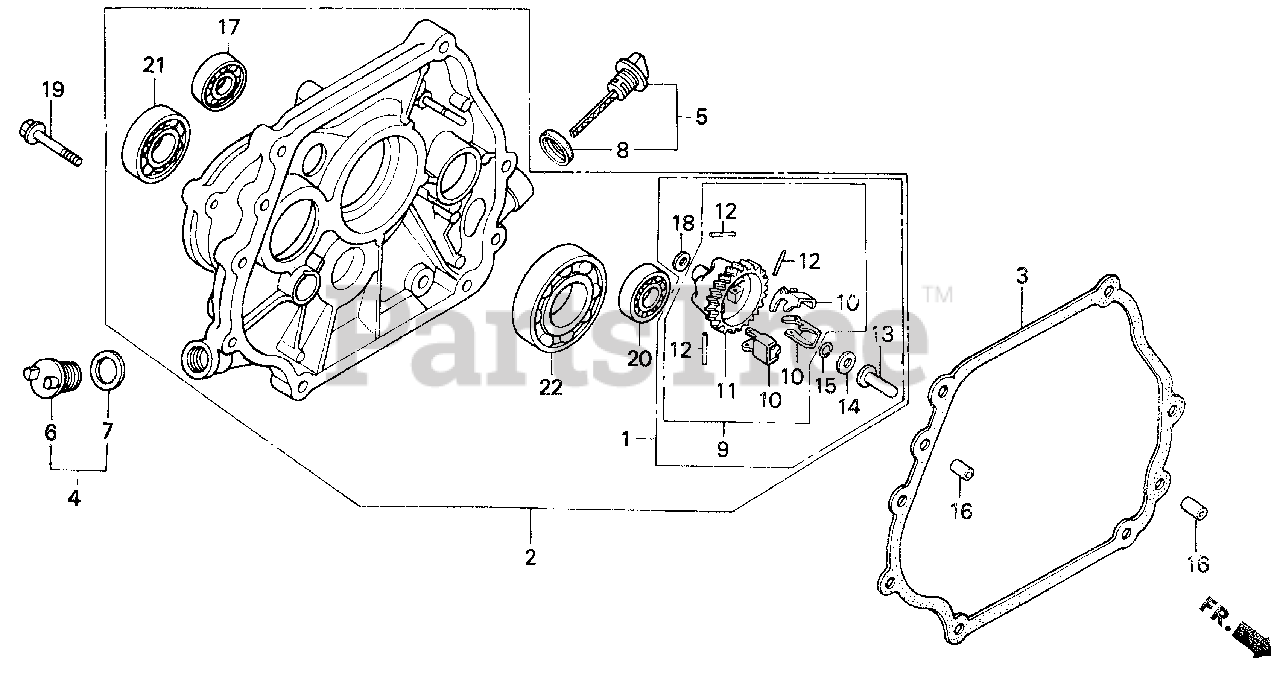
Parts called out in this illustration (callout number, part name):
1	GOVERNOR KIT
2	COVER ASSY., CRANKCASE (L-TYPE)
3	GASKET, CASE COVER
4	CAP ASSY., OIL FILLER
5	CAP ASSY., OIL FILLER
7	GASKET, OIL FILLER CAP
8	GASKET, OIL FILLER CAP
9	GOVERNOR ASSY.
10	WEIGHT, GOVERNOR
11	HOLDER, GOVERNOR WEIGHT
12	PIN, GOVERNOR WEIGHT
13	SLIDER, GOVERNOR
15	CLIP, GOVERNOR HOLDER
16	PIN, DOWEL (8X12)
17	BEARING, RADIAL BALL (6202)
18	WASHER, PLAIN (6MM)
19	BOLT, FLANGE (8X40)
20	BEARING, RADIAL BALL (6202)
21	BEARING, RADIAL BALL (6204)
22	BEARING, RADIAL BALL (6207)
